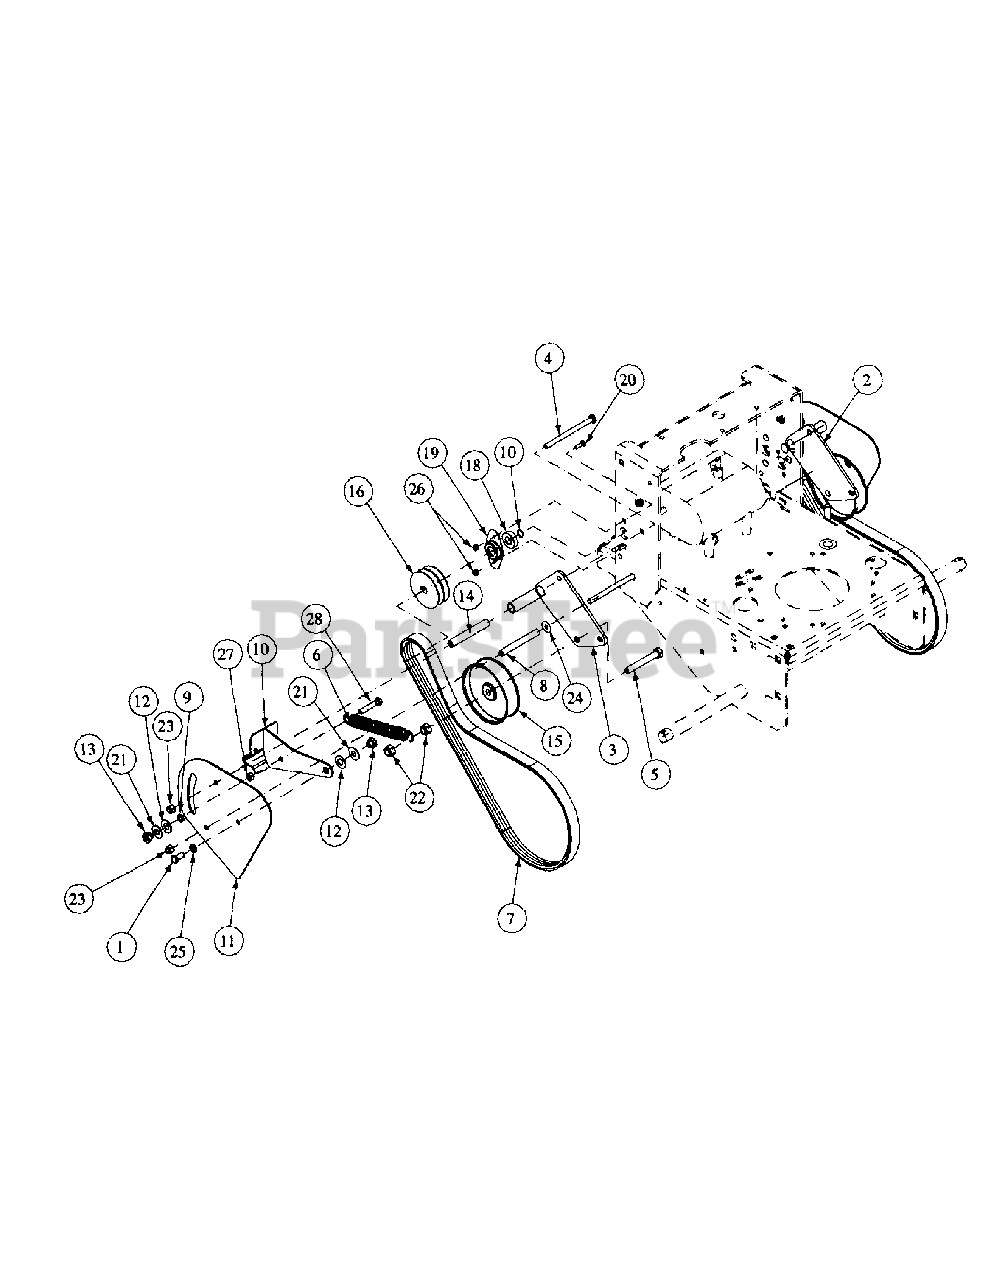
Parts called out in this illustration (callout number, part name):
1	Hex Cap Screw, 3/8-16, .875
2	Left Idler Bracket
3	Right Idler Bracket
4	Carriage Bolt, 3/8-16 x 5.50
5	Hex Cap Screw, 1/2-13, 3.50
6	Extension Spring
7	Belt, V
8	Spacer Tube
9	Roller Tube
10	Spring Adjust
11	Belt Guard
12	Slide Washer
13	Shoulder Nut
14	Idler Sleeve
15	Flat Idler Drive
16	Jackshaft Pulley
17	External Retain Ring
18	Bearing
19	Bearing Housing
20	Carriage Bolt, 1/4-20 x .750
21	Washer, 1/2 x 1
22	Lock Nut, Nylon Insert, 1/2-13
23	Lock Nut, Nylon Insert, 3/8-16
24	Flat Washer, 3/8 Zinc
25	Lock Washer, 3/8 Zinc
26	Lock Nut, Nylon Insert, 1/4-20
27	Hex Nut, 3/8-16
28	Hex Cap Screw, 3/8-16, 2.00
